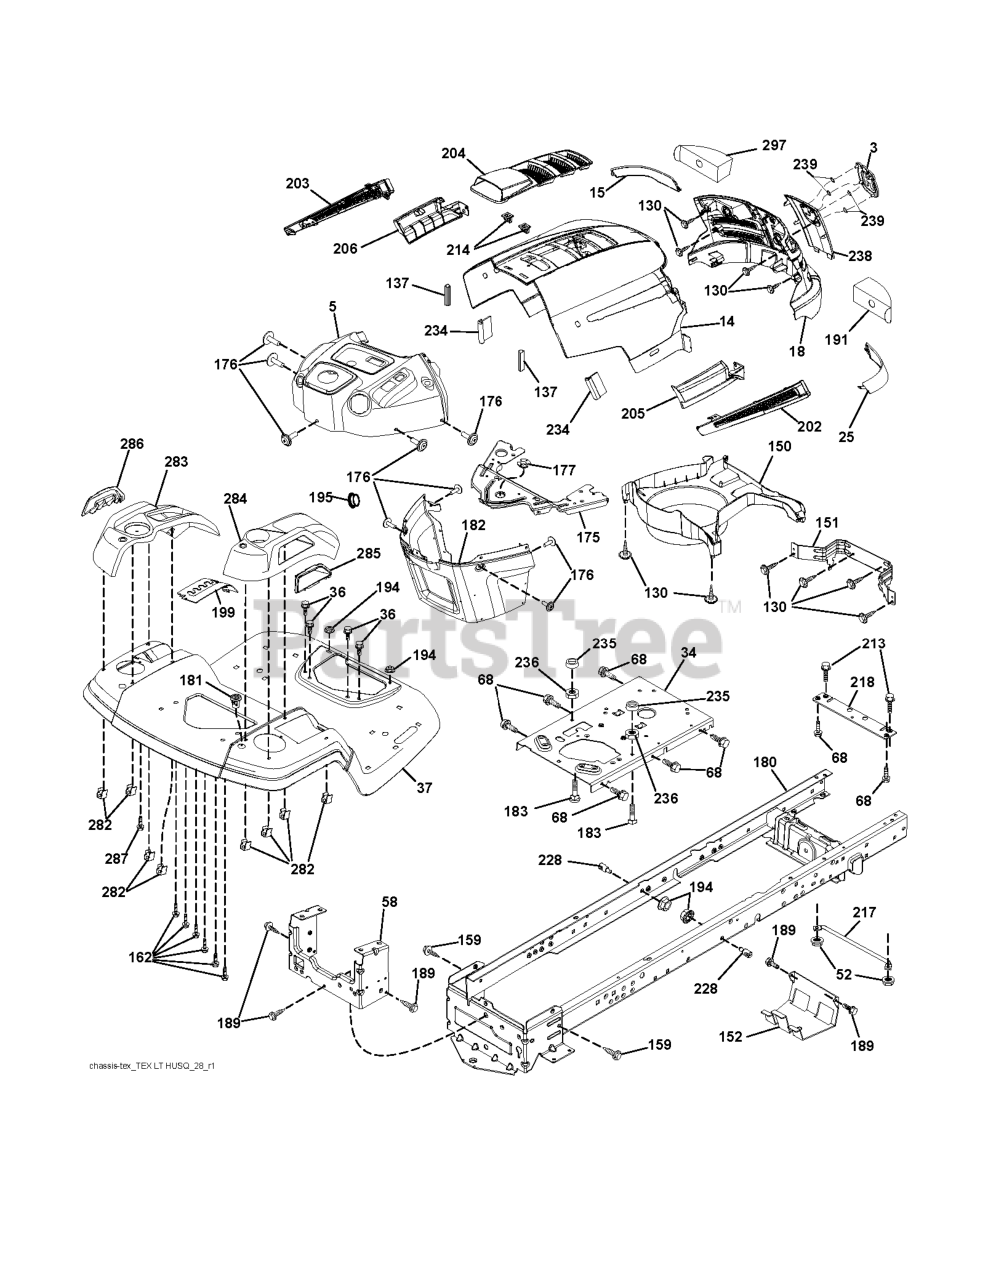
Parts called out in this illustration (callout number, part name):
3	RP LOGO
5	DASH
14	HOOD.HUSQVARNA.LT.ORANGE
15	LENS.HUSQVARNA LT.LH
18	GRILLE.SVC.HUSQVARNA.LT.GREY
25	LENS.HUSQVARNA LT.RH
34	PLATE.ENGINE.WELDED.CHASSIS
36	SCREW 5/16"
37	FENDER.TLT.FS.W/CUPHLD.ORANGE
52	LOCKNUT
58	DRAWBAR UPPER 2PC SMALL FENDER
68	Screw 5/16-18 x 1/2 Hex, Self Tapping 5/16-18 x 1/2
130	SCREW.#10 X 0.750.BOS
137	BUMPER DASH
151	BRACKET PIVOT
152	SHIELD.BROWNING.W/TEX
159	SCREW, 3/8-16X3/4
162	SCREW.HI-LO.CONSOLE
175	CROSSMEMBER
176	SCREW.#10-24X5/8.RN.QU
177	BUSHING STEERING
180	CHASS.WLDMNT.TL.12GA/2P.48/54
182	DASH.LOWER.PREDATOR LT
183	BOLT.5/16-18X1-1/4 FULL THD
189	SCREW
191	INSERT.REFLECTIVE.RH.
194	NUT LOCK HEX FLANGE 5/16-18
195	PLUG DASH
199	PLATE.DECK.LIFT.HUSQ.LT
202	VENT SIDE HOOD LH
203	VENT SIDE HOOD RH
204	VENT TOP HOOD
205	SKIRT SIDE RH
206	SKIRT SIDE LH
213	BOLT
214	CLIP.RETAINER.TINNER.
217	ROD.PIVOT.HOOD
218	X-PIECE.HOOD.STOP.NON/
228	STUD.FASTNER.W/ANTI-ROTATE
234	BUMPER.HOOD.TEX.HUSQVARNA
235	SPACER FENDER
236	NUT.CENTERLOCK.5/16-
238	TRIM
282	CLIP.RETAINER.CONSOLE.LT.HUSQ
283	CONSOLE.DECK.LIFT.HUSQ.N/FR.GR
285	CONSOLE INSERT RH
286	CONSOLE.INSRT.LH.HUSQ.LT.BLACK
287	SCREW 1/4X20
297	INSERT REFLECTIVE
